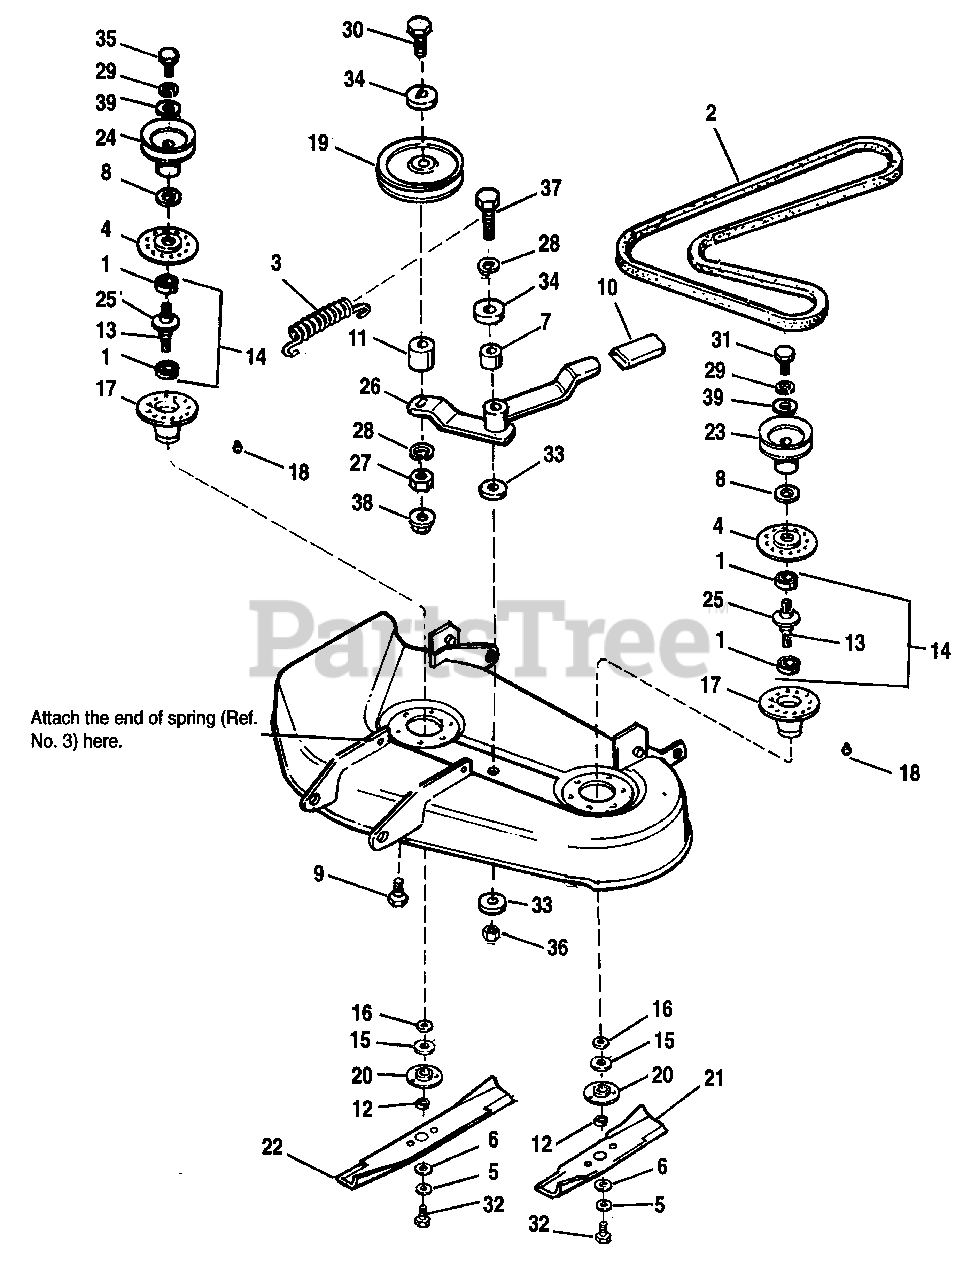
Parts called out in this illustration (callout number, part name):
2	V-BELT, 82-7/64"
4	COVER, Arbor Housing
5	WASHER, Spring
6	WASHER, Spline
8	SHIELD, Bearing Upper, Arbor
9	SCREW, Taptite, 5/16-18 x 3/4
10	GRIP, Lever
12	COLLAR, Mower Arbor
13	SHAFT, Arbor
14	SHAFT & BEARING ASSY., (Incl. Ref. Nos. 1 & 13)
15	SHIELD, Grass, Bottom
16	WASHER, Shim
17	ARBOR HOUSING ASSY. (Incl. Ref. No. 18)
18	FITTING, Grease
19	IDLER, Backside
20	ADAPTOR, Blade
21	BLADE, Mower, Small (14-27/64")
22	BLADE, Mower, Large (19-3/16")
23	PULLEY ASSY., Small Blade
24	PULLEY ASSY., Large Blade
25	GASKET, Foam
26	LEVER ASSY.
27	NUT, Hex, 3/8-16
28	LOCKWASHER, 3/8
29	LOCKWASHER, 7/16
30	CAPSCREW, Hex Hd., 3/8-16 x 2-1/2
31	CAPSCREW, Hex Hd., 7/16-14 x 1-1/4, Gr. 8
32	CAPSCREW, Hex Hd., 7/16-14 x 1, Gr. 8
33	WASHER, Flat, 3/8 x 1/8
34	WASHER, Flat, 3/8
35	CAPSCREW, Hex Hd., 7/16-14 x 2, Gr. 8
36	NUT, Hex, 3/8-16
37	CAPSCREW, Hex Hd., 3/8-16 x 2-3/4
38	NUT, Hex, Flange Lock, 3/8-16
39	WASHER
